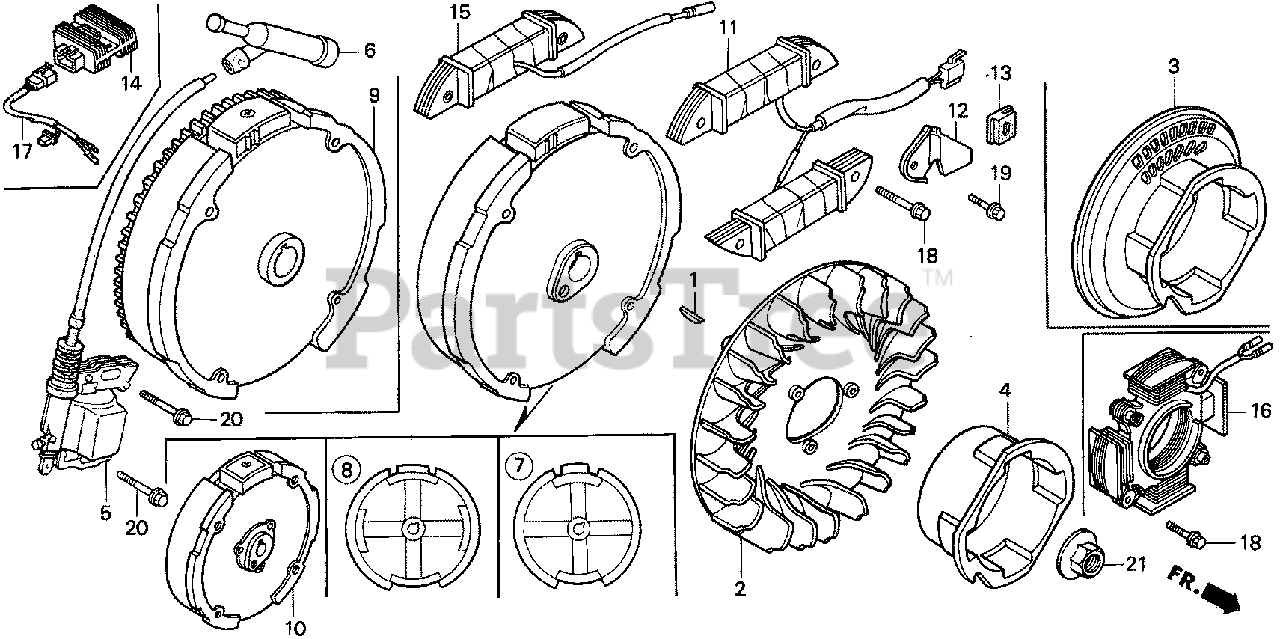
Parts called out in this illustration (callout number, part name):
1	KEY, SPECIAL WOODRUFF (25X18)
2	FAN, COOLING
4	PULLEY, STARTER
5	COIL ASSY., IGNITION
6	CAP ASSY., NOISE SUPPRESSOR
8	FLYWHEEL (LAMP)
11	COIL ASSY., LAMP (12V/50W)
12	CLAMP, WIRE
13	GROMMET, WIRE
18	BOLT, FLANGE (6X28)
19	BOLT, FLANGE (5X10)
20	BOLT, FLANGE (6X25)
21	NUT, SPECIAL (14MM)
